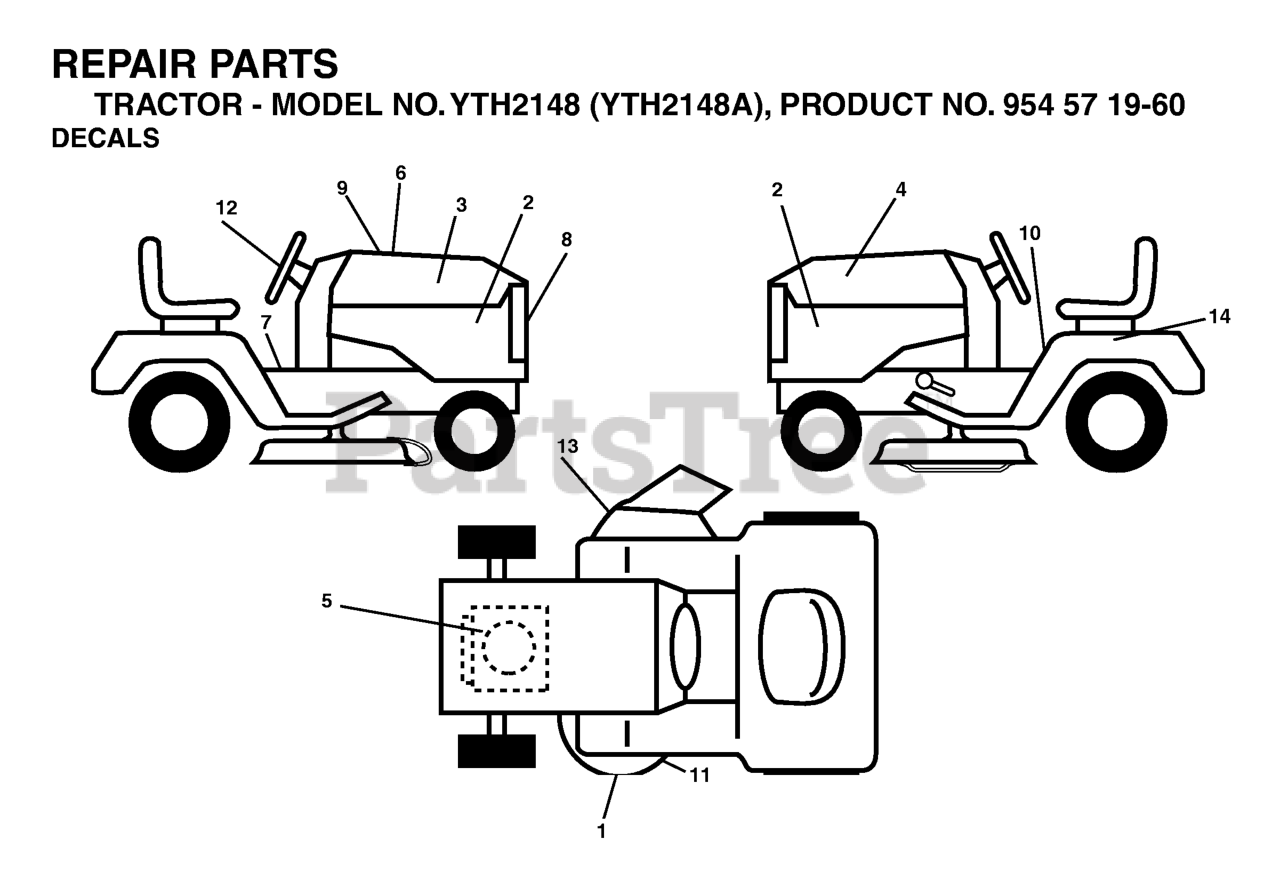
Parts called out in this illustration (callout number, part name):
6	DECAL HOOD CUST. RESP.
10	DECAL FENDER DANGER
11	DECAL V-BELT SCHEMATIC
12	DECAL.STEERING.HUSQ.BLUE
13	DECAL.WARN.KEEP.HAND.AWAY
14	DECAL BTRY SYMBOLS
